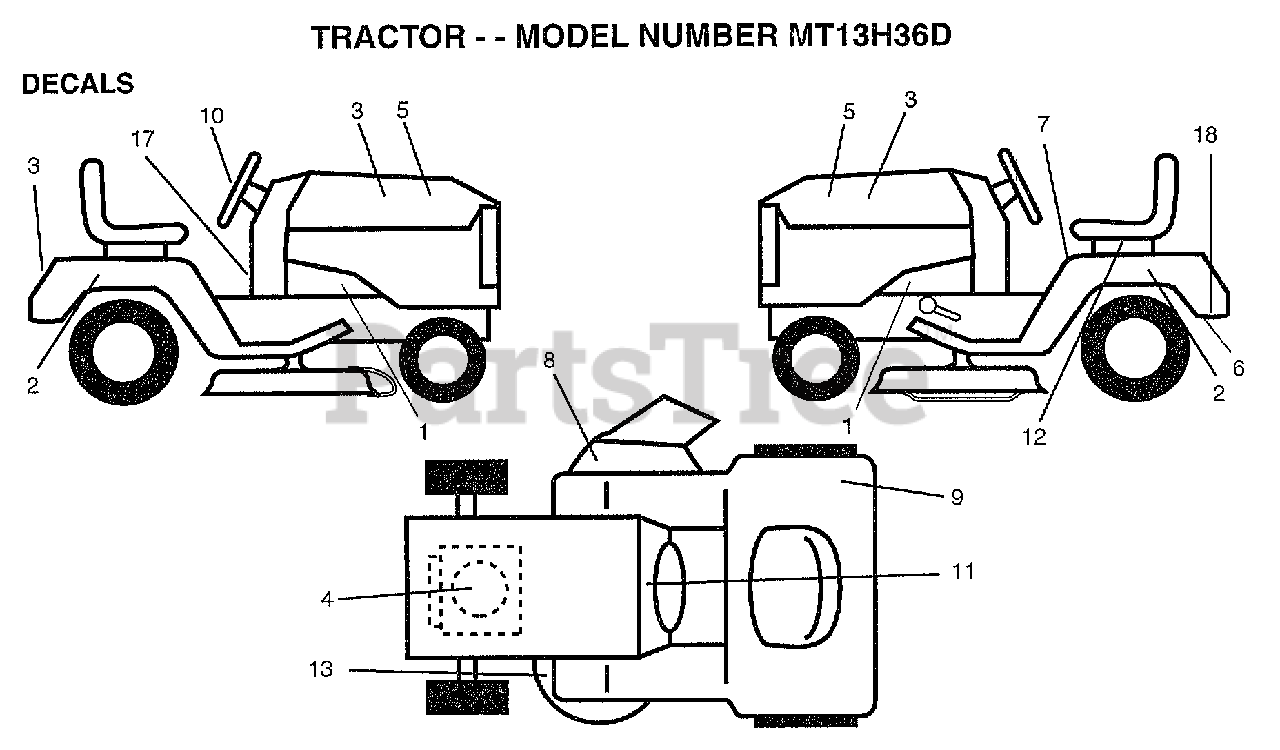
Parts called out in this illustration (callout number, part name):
1	"DECAL CHASSIS,HOT"
2	"DECAL-FENDER,AUTO"
3	NAMEPLATE.MOTEC.S
4	DECAL.HP.ENG.B&S13HP
5	"DECAL-HHD,MTC300Y"
6	DECAL.DRAWBAR.LDL
7	DECAL.READ.O.MANU
8	DECAL.DANGER.CUTF
10	"DECAL-WHEEL,STEER"
11	DECAL CLUTCH/BRAK
12	DECAL.BATRY.3-3908
13	DECAL.V.BELT
17	DECAL.EURO.ST.CE.
18	DECAL.DRAWBAR.CTL
